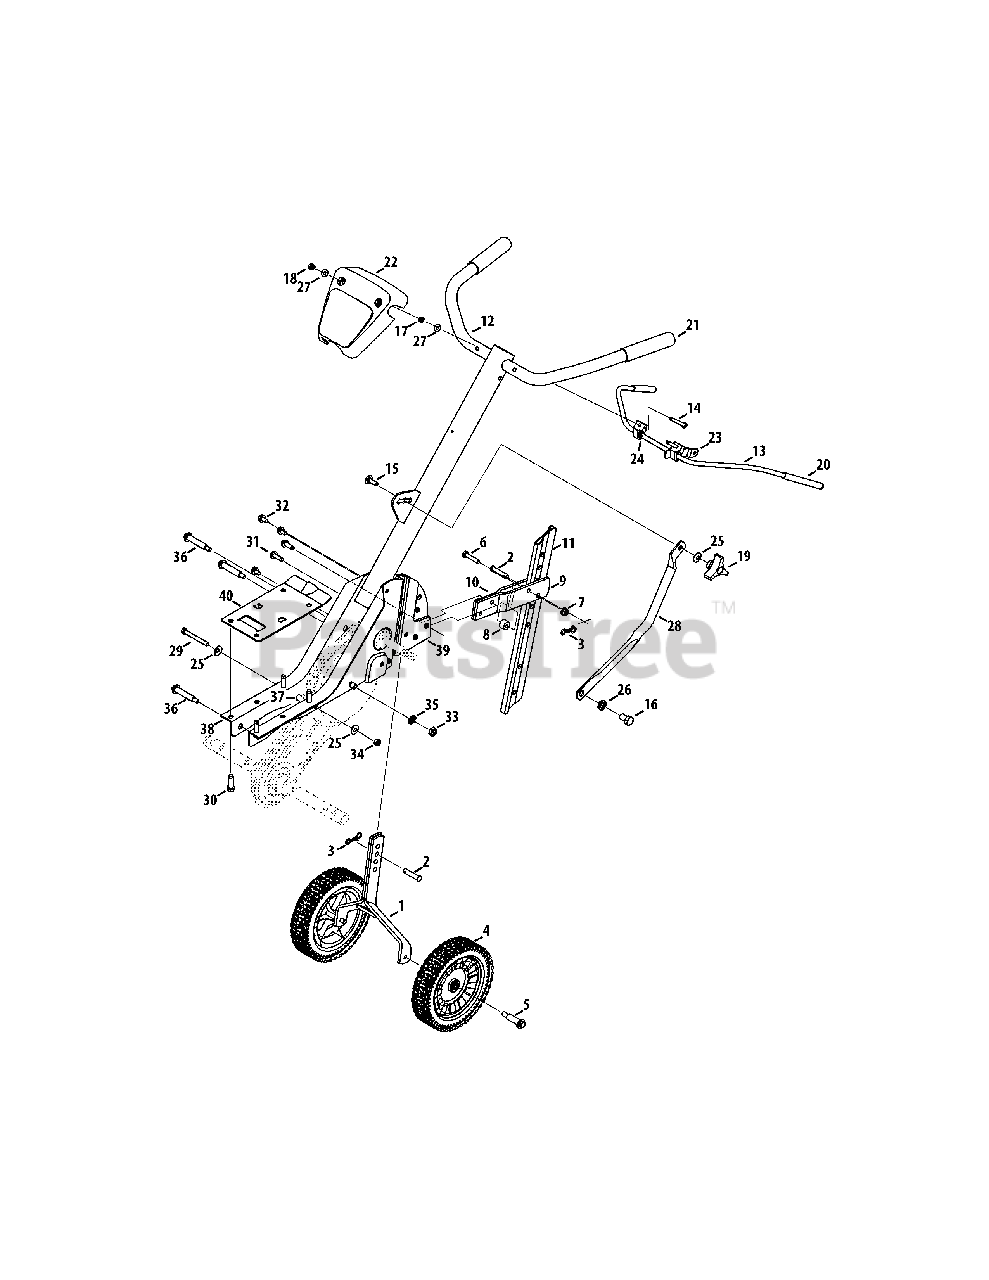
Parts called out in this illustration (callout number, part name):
1	Wheel Bracket Assembly
2	Clevis Pin, .375 x 1.75
3	Bow Tie Cotter Pin
4	Complete Wheel Assy. 8 x 1.75
5	Shoulder Screw, .496 x 1.445 3/8-16
6	Hex Head Screw, 5/16-18 x 1.50
7	Nut, 5/16-18, Flange Lock
8	Spacer, .325 ID x .75 OD x .520
9	Tail Bracket, LH
10	Tail Bracket, RH
11	Depth Bar
12	Complete Handle Assembly
13	Clutch Bail
14	Hex Head Screw, 1/4-20 x 2.25
15	Carriage Screw, 5/16-18 x 1.00
16	Hex Head Screw, 1/2-20 x .750
17	Jam Nut, 1/4-20
18	Nut, 1/4-20, Lock
19	Handle Knob
20	Grip, Clutch Bail
21	Grip, Handle
22	Handle Cover
23	Clutch Bail Holder
24	Flat Washer, .385 x .62 x .063
25	Bell Washer, .340 x .872 x .060
26	Lock Washer, 1/2
27	Flat Washer, .271 x .630 x .065
28	Handle Brace
29	Hex Head Screw, 5/16-18 x 2.75
30	SEMS Screw, 3/8-16
31	Self-Tapping Screw, 5/16-18 x 1.00
32	Self-Tapping Screw, 5/16-18 x .625
33	Jam Nut, 7/16-20
34	Hex Lock Nut, 5/16-18
35	Lock Washer, 7/16
36	Shoulder Screw, .475 x 2.11 5/16-18
37	Spacer, .47 OD x .96
38	Frame, RH
39	Frame, LH
40	Engine Mounting Plate
